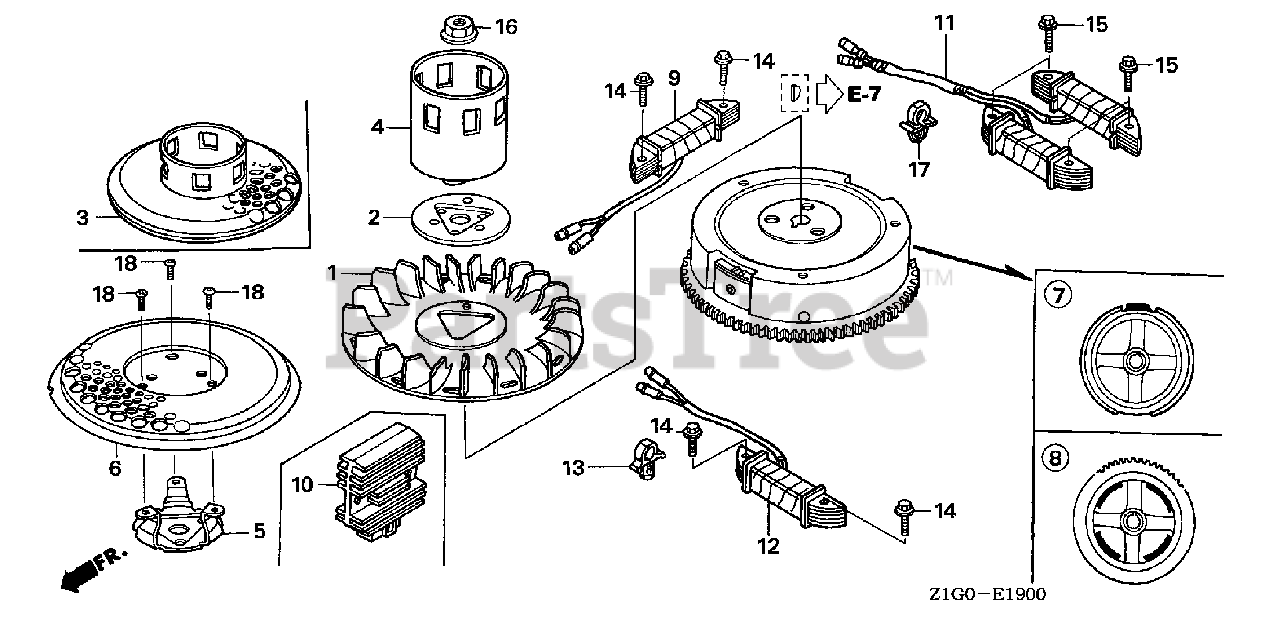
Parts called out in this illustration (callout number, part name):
1	FAN, COOLING
2	PLATE, COOLING FAN SETTING
8	FLYWHEEL (SEL-4POLE)
9	COIL ASSY., CHARGE
14	BOLT, FLANGE (6X28) (CT200)
16	NUT, SPECIAL (16MM)
